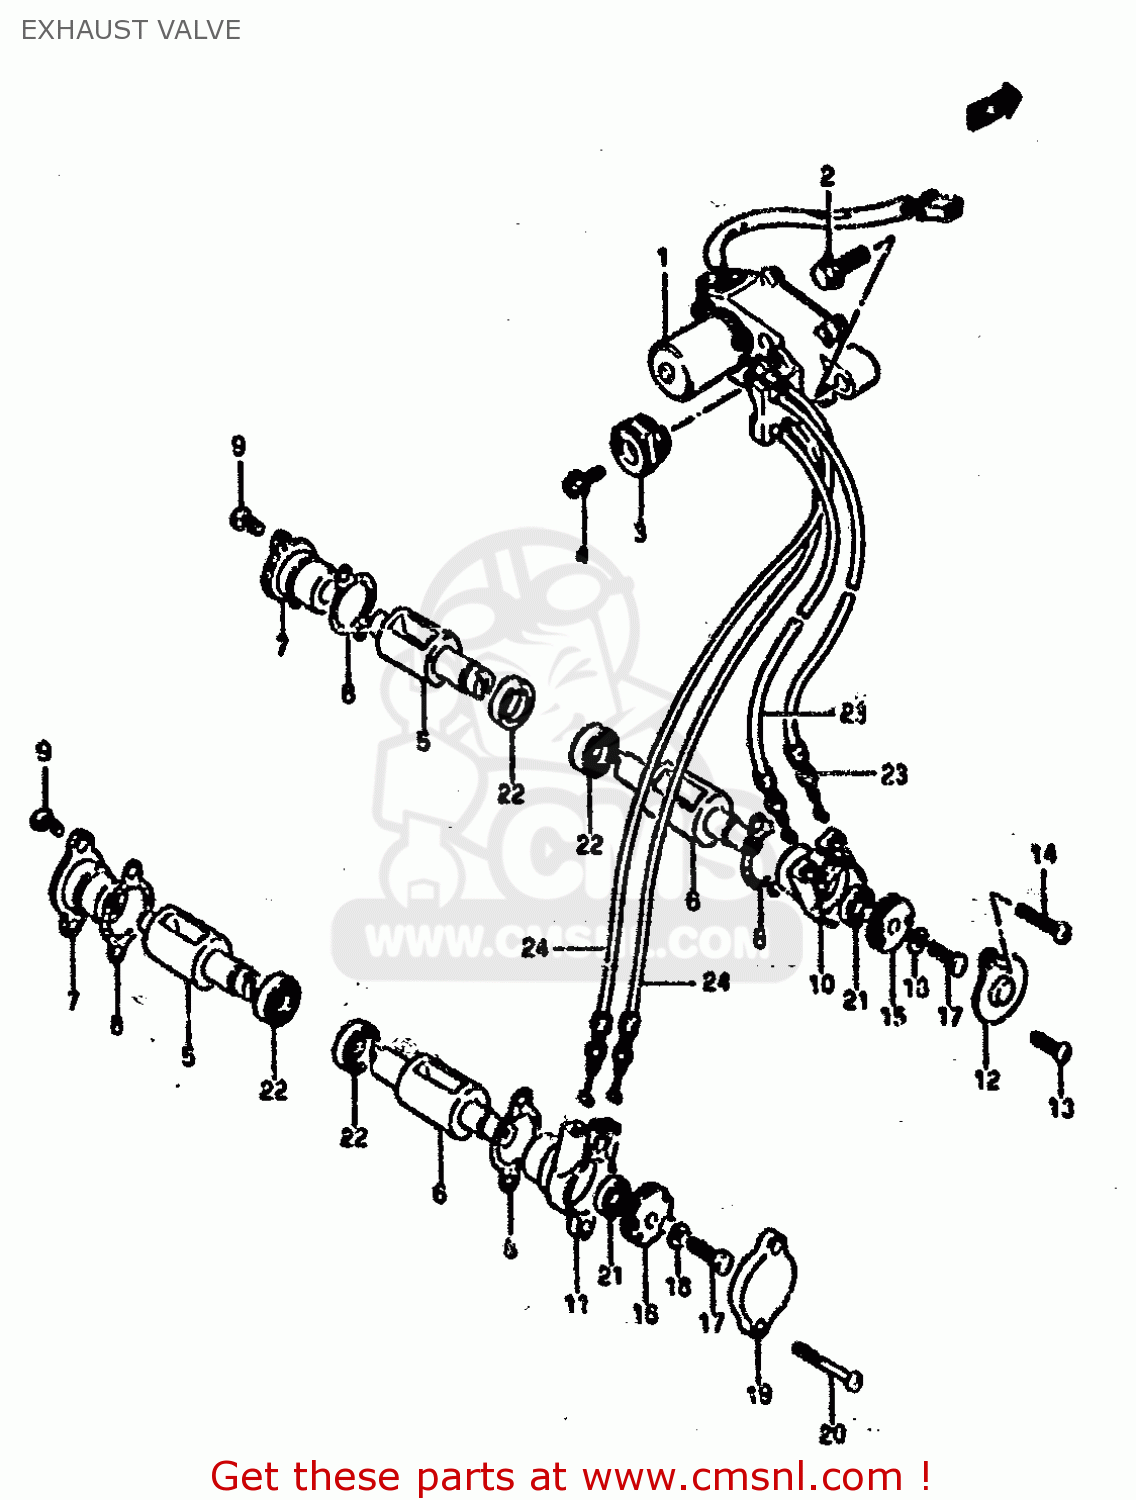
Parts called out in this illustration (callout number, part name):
1	ACTUATOR ASSY,EXHAUST VALVE
2	BOLT
3	PULLEY,CONTROLLER
4	BOLT
5	VALVE,EXHAUST LH
6	VALVE,EXHAUST RH
7	CAP,EXHAUST VALVE
8	GASKET, EXHAUST VALVE (MCA)
9	SCREW
10	HOLDER,EXHAUST VALVE NO.1
11	HOLDER,EXHAUST VALVE NO.2
12	PLATE,HOLDER
13	SCREW
14	SCREW
15	PULLEY,EXHAUST VALVE FRONT
16	PULLEY, EXHAUST VALVE
17	BOLT
18	WASHER
19	COVER,HOLDER
20	SCREW
21	SEAL,OIL(12X22X5)
22	SEAL,OIL(16X26X7)
23	CABLE ASSY,EXHAUST VALVE
24	CABLE ASSY,EXHAUST VALVE RR
